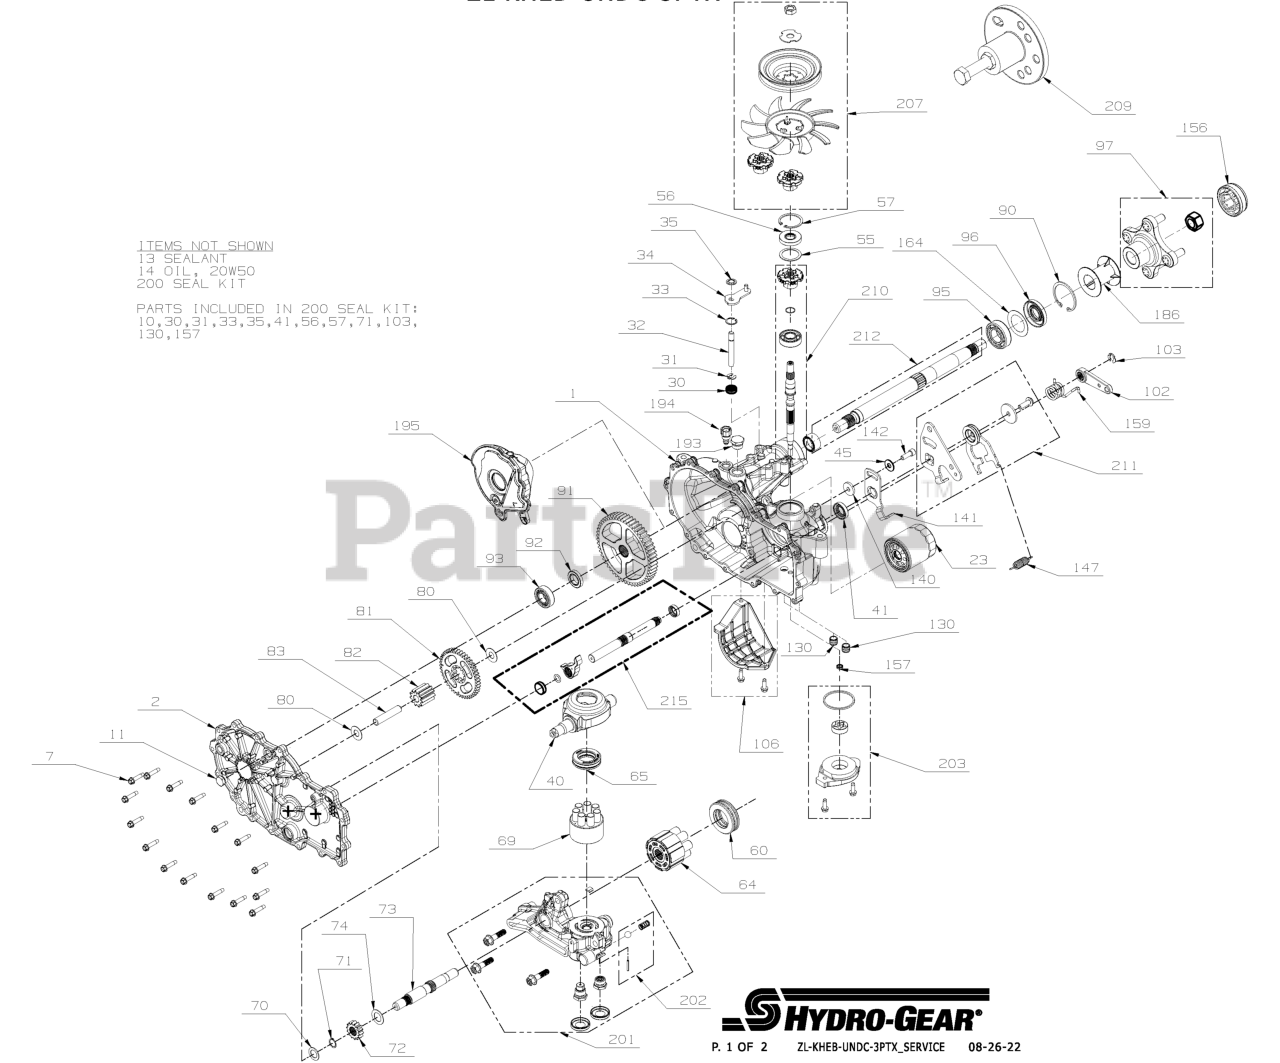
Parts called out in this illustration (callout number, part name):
1	KIT, HOUSING, MAIN, LH, CHRG, CNTL
2	KIT, SIDE COVER, LH
7	SCREW,HEX WASHER 1/4-20X1.125
11	PLUG EXT HEX VENT 9/16 18
13	SEALANT TUBE 10.1OZ.
14	FLUID, HYDRO 15W50 QT
14	FLUID, HYDRO 20W50 QT
23	FILTER, HYDRO-GEAR 2800 TRANS
30	Seal, lip .375 x 375 x 325
31	RING. RETAINING
32	ROD, BYPASS
33	RING, RET .750
34	HG BYPASS ARM (52370)
35	RING, RTNG .
40	TRUNNION, SWASHPLATE
41	SEAL, LIP 18X32X7
55	WASHER 1.23X1.56X.04
56	SEAL, LIP 17 X 40 X 7 HNBR
57	RING, RET 1.56 INT
60	HG THRUST BEARING (51462)
64	HG 16CC CYLINDER BLOCK (71579)
65	BEARING. THRUST 30 X 52 X 13
69	ASSY, BLOCK 7 PISTON
70	WASHER .63X1.0X.05
71	RING, RET 62 EXT
72	GEAR 14T STEEL
73	SHAFT, MOTOR
74	WASHER .71 X 1.16 X .04
80	WASHER .5X1.0X.032
81	GEAR 45 TOOTH
82	GEAR 11 TOOTH STEEL
83	HFHCS 1/4-20X.875
90	RING, RETAINING
91	GEAR 54 TOOTH
92	SPACER
93	KIT, BEARING
95	BEARING, BALL 25.4 X 52 X 15
96	SEAL, LIP
97	KIT, HUB 4 BOLT
102	HANDLE- ACTUATING
103	CLIP,BRAKE ARM HYDROGEAR 52027
106	KIT, FILTER GUARD
130	TUBE CHARGE TRIPLE ORING
141	ARM, NEUTRAL LEFT
142	SHCS 5/16-24X1 PATCH
156	CAP, AXLE
157	KIT GEROTOR SEAL
159	SPRING, TORSION CCW
164	WASHER, 1.355 x 2.035 x .021 FLAT
186	TUBE, AXLE 2.03
194	ASSEMBLY, FITTING 9/16-18 BREATHER
195	ASSEMBLY, TANK, EXPANSION, INTERNAL, LH
200	KIT, SEAL
201	KIT, CENTER SECTION, LH CHARGE
202	KIT CHARGE RELIEF
203	KIT, CHARGE
207	KIT- FAN/PULLEY
209	HUB PULLER 5 BLT
210	KIT INPUT SHAFT
211	RING, RTNG .
212	KIT, SHAFT, AXLE
215	KIT, OUTBOARD, RH ROT A / LH ROT B
